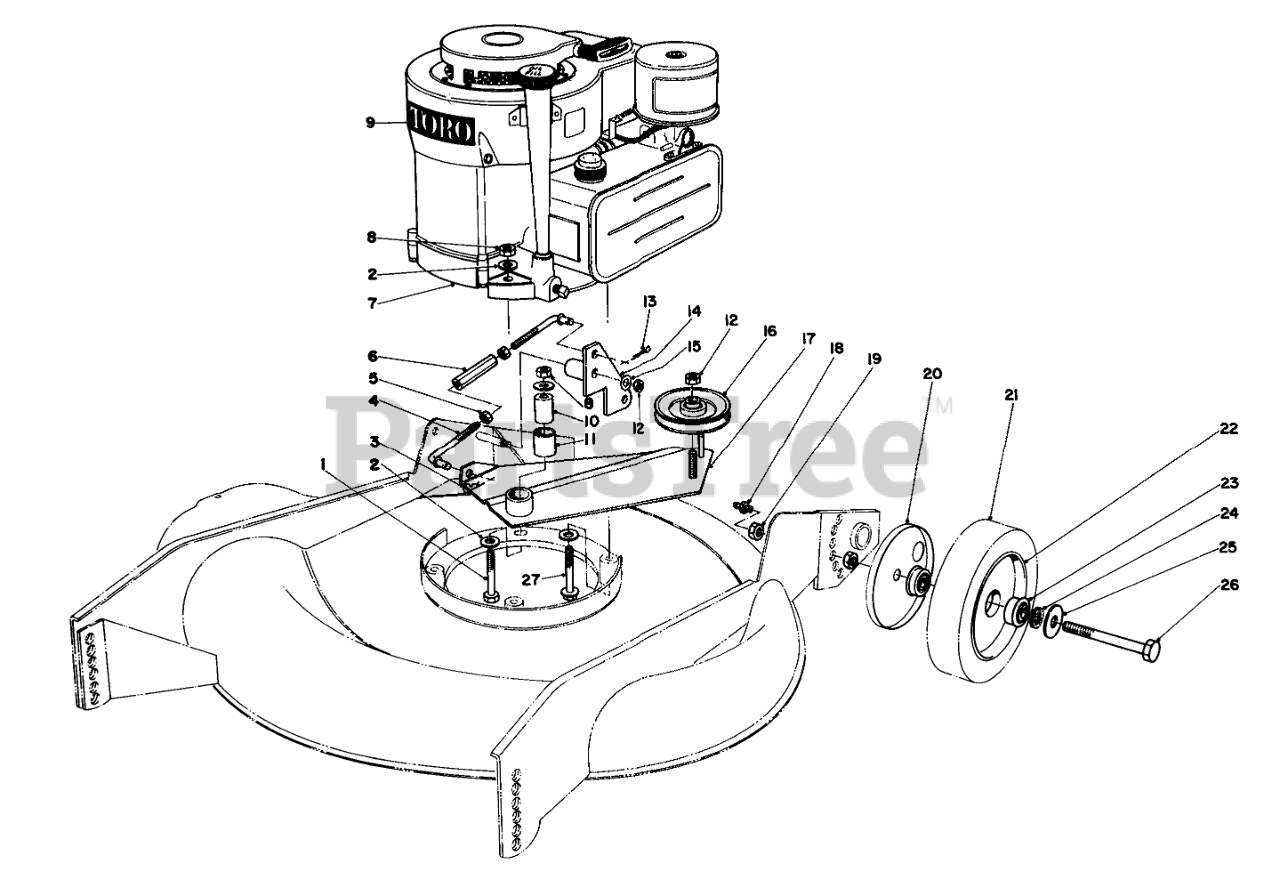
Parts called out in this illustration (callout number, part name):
1	SCREW-HH
2	WASHER-PLAIN
3	HAIRPIN COTTER
4	CONTROL ROD LINK
5	NUT-KEPS
6	CONTROL ROD SLEEVE
7	Engine
8	Nut
9	Decal Toro
10	Pedestal
11	BUSHING
12	NUT-HEX
13	PIN-COTTER
14	BELL CRANK WA
15	WASHER-FLAT
16	IDLER PULLEY R
17	Idler Arm (Incl. Ref. #11)
18	FITTING-GREASE
19	NUT-HEX
20	WHEEL COVER
22	Wheel & Tire Assembly, Rear (Incl. Ref. #21 & 23)
23	BEARING-BALL
24	FELT WASHER
25	WASHER-FLAT
26	WHEEL BOLT REAR
27	3/8-16 X 2-3/4 CAPSCR
